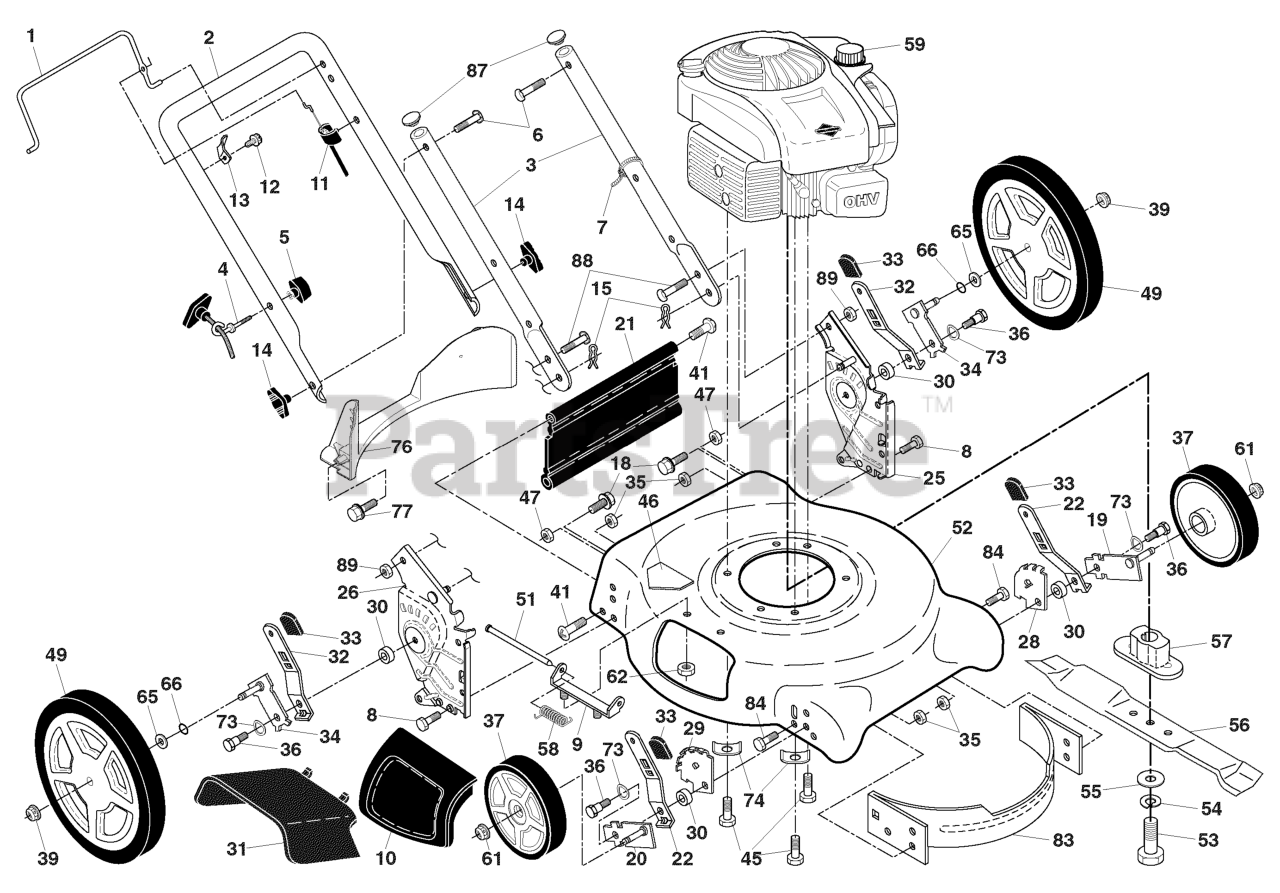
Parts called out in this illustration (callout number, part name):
1	Control Bar
2	Upper Handle
3	Bar, Lower Handle
4	GUIDE, Rope
6	Bolt, Carriage 1/4-20 x 1-1/2
7	Wire, Tie
8	Bolt, Hex Head 5/16-18 x 3/4
9	Hinge Bracket
10	Mulcher Door
11	Engine Zone Control Cable
12	SCREW, Hex Head, Threaded, Rolled, #10-16 x 5/8
13	Up-Stop Bracket
14	Knob, Handle
15	Cotter, Hairpin
18	SCREW, Hex Washer Head, 1/4-20 x 3/8
19	Axle Arm Assembly, Left Front & Right Rear
20	Axle Arm Assembly, Right Front & Left Rear
21	Kit, Rear Skirt
22	Selector Spring, Front
23	Rear Door Assembly
25	HANDLE BRACKET ASSEMBLY, Left Hand
26	HANDLE BRACKET ASSEMBLY, Left Hand
28	Wheel Adjusting Bracket, Front, LH
29	Wheel Adjusting Bracket, Front, RH
30	Spacer
31	Discharge Defl ector
32	Selector Spring, Rear
33	Knob, Selector Spring
34	HANDLE BRACKET ASSEMBLY, Left Hand
35	NUT, Hex, Flangelock 5/16-18
36	BOLT, Shoulder, 5/16-18 x .33
37	HANDLE BRACKET ASSEMBLY, Left Hand
39	Nut, Hex, Flangelock 3/8-16
41	Screw, Hinge
45	Screw, Hex Head, Threaded, Rolled, 3/8-16 x 1-1/5
46	Decal Deflect WRN. Cutfinger
47	Locknut, Hex 5/16-18
49	HANDLE BRACKET ASSEMBLY, Left Hand
51	Hinge Rod
52	Kit, Lawn Mower Housing
53	Screw, Machine, Hex Head, 3/8-24 x 1-3/8, Grade 8
54	Washer, Lock Hvy Hlcl Spr 3/8
55	WASHER, Hardened
56	Blade, 21"
57	Blade Adapter
58	Hinge Spring
59	ENGINE, Briggs & Stratton
61	NUT, Hex, Flangelock 3/8-16
62	LOCKNUT, Hex, 1/4-20
65	WASHER, Flat, 3/8
66	O-Ring
73	Washer, Curved, Cylindrical
74	Washer, Special, Engine
76	Baffle, Rear
77	Screw, Hex Washer Head, #13 x 3/4
83	Baffl e, Front
84	Screw, Hex Head 5/16-18
87	Plug, Lower Handle Bar
88	BOLT, Hex Head
89	Nut, Hex
